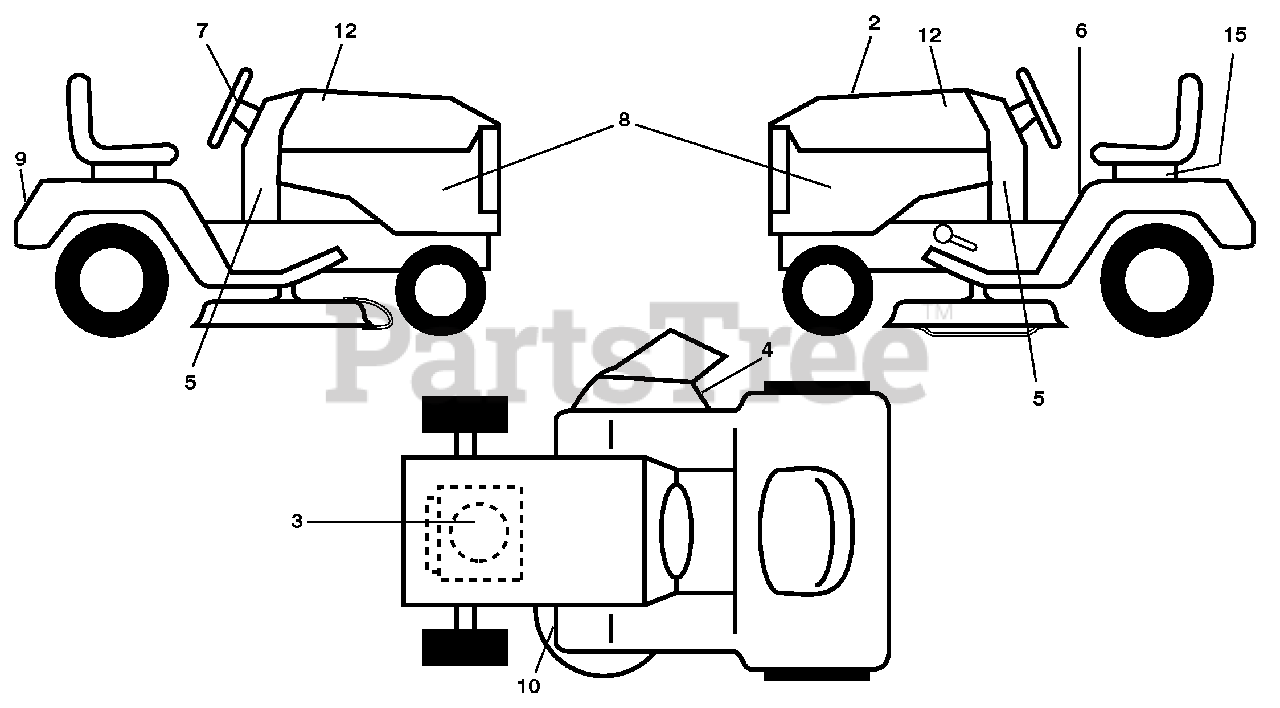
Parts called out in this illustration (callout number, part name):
2	Decal, Replacement
3	Decal, Engine HP
4	Decal, Warning
5	Decal, Dash Lower
6	Decal, Fender Warning (E&F)
7	Decal, Ins Str Wh
8	Decal, Side Panel
9	Decal, Fender
10	Decal, V-Belt Sch.
12	Decal, Hood RH/LH
15	Decal, Caution, Battery
15	Pad Footrest RH
15	Pad Footrest LH
15	Decal, Handle Lft Height Adj.
15	Manual, Operator's, English & French
15	Manual, Parts, English & French
15	Manual, Operator's Spanish
